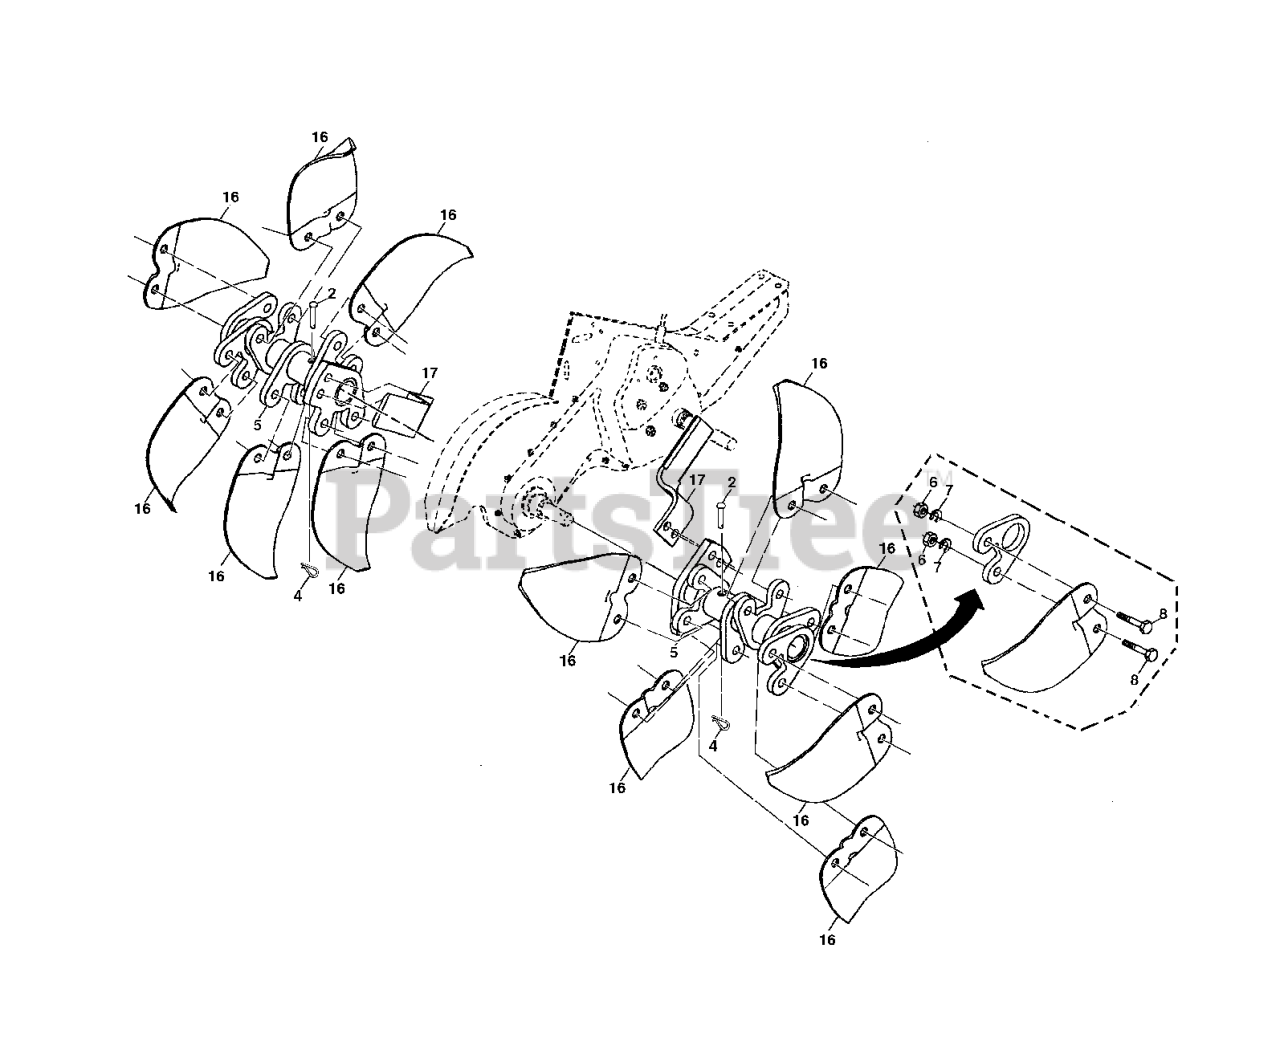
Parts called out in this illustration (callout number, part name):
2	PIN RETAINING SCREW
4	SPRING RETAINER
5	HUB.ASM.DRT17.2004 (CMPL KIT)
6	NUT
7	WASHER, LOCK 3/8
8	BOLT.HEX.001X20.37-24X1.ZINC
16	TINE.SPADE
17	TINE.CLEANING BLACK
